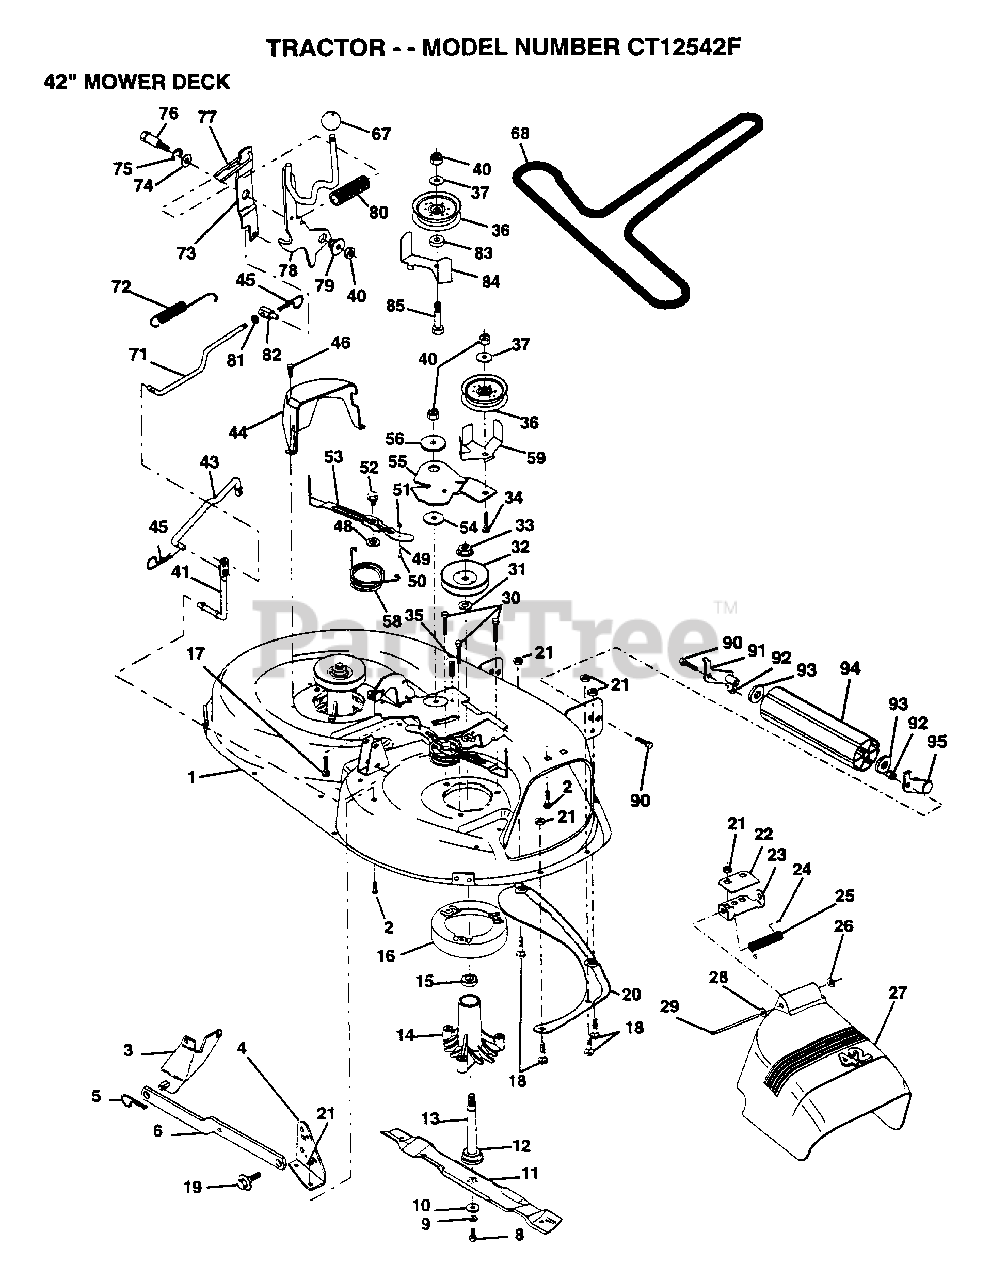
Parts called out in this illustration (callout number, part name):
1	DECK.WELD.42.
2	BOLT
3	BRKT ASM SWAY BAR
4	BRKT DECK SW BAR
8	BLADE BOLT
10	WASHER.HARD.BLADE
11	"BLADE.42"" HIPERF"
12	BEARING.BALL
14	HSG ASM MANDREL
15	BEARING
16	STRIPPER RND MWR
17	BOLT RDHD 3/8-16
18	BOLT
19	BOLT SHD 5/16-18
22	STIFFENER BRKT
23	DEFLECTOR BRKT
24	CAP-SLEEVE LT
25	SPRING TORSION
26	NUT PUSH M
27	DEFLECTOR.SHIELD
28	WASHER
29	HINGE ROD
31	WASHER
34	BOLT
35	XMAS TREE FASTNER
36	FLAT IDLER PULLEY
37	WASHER
41	PIVOT ROD
43	ROD CLUTCH W/NIBS
44	GUARD MAND LH BLK
45	RETAINER M
46	SCREW.1/4-20X5/8
48	HARD SMALL WASHER
50	SHOULDER BOLT
51	LOCKNUT
52	BOLT.SHLD.5/16-18
53	BRAKE PAD ARM ASM
54	HARDENED WASHER
56	SPACER RETAINER
58	SPRING TORSN BRAK
59	GUARD IDLER TUV
67	CONTROL KNOB LT
68	BELT.V.T-PATH
71	ROD CLUTCH 38/42
72	RETURN SPRING
73	CLUTCH ARM SECOND
74	WASHER
75	RING
76	SHOULDER BOLT
77	SPRING KEEPER
78	LEVER ASM CLT PRM
79	BUSHING
81	NUT
82	TRUNION ADJ
83	WASHER
85	BOLT
90	BOLT
92	NUT
93	WASHER
